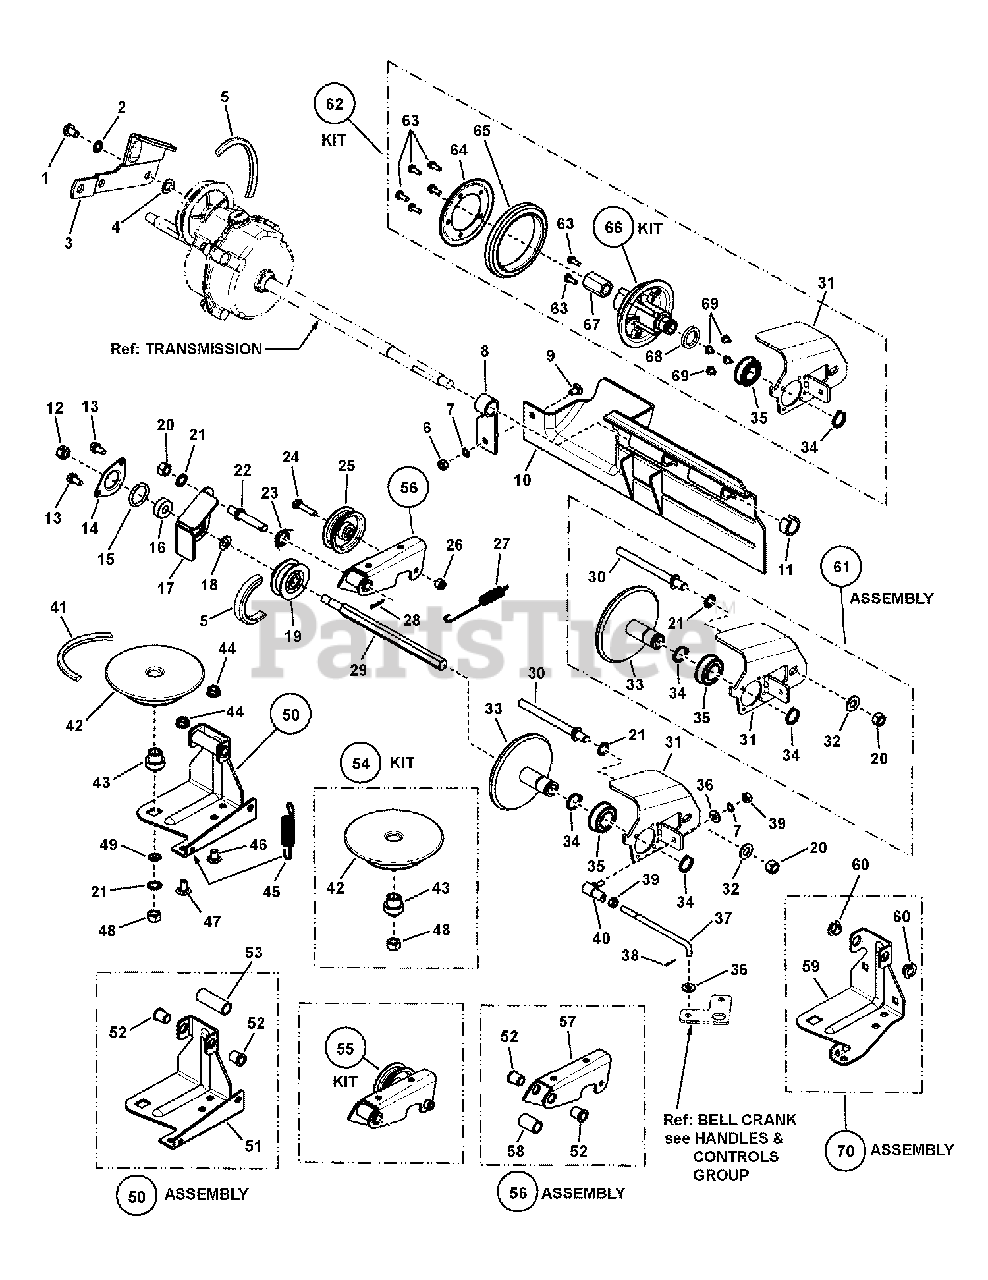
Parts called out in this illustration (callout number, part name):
1	SCREW, 5/16-18 x 1/2" Pan Head Self-Tap (Torx)
2	WASHER, 5/16" Internal Tooth Lock
3	LINK, Differential (Comm.)
4	WASHER, 44 x .78 x .025 Curved
5	BELT, Poly-V
6	NUT, 1/4-20 Hex, GR 5
7	WASHER, 1/4" Internal Tooth Lock
8	SUPPORT, Foot Guard
9	BOLT, 1/4-20 x 1/2" Short Neck Carriage GR 5
10	FOOT GUARD, Rear
11	RING, Split (Black)
12	NUT, 3/8-24 Hex Center Lock, GR 5
13	SCREW, 1/4-20 x 1/2" Hex Flange Self-Tap
14	HOLDER, Bearing (Outer Half)
15	O-RING, V21
16	BALL BEARING, Spherical O.D., .38 I.D.
17	HOLDER, Bearing (Inner Half)
18	WASHER, .390 I.D. Flat
19	PULLEY, Poly-V (2" O.D.)
20	NUT, 3/8-24 Hex
21	WASHER, 3/8" Internal Tooth Lock
22	STUD, Idler (3/8-24 thread)
23	SPRING, Idler- Torsion
24	SCREW, 1/4-28 x 1-3/8" Hex Head Cap, GR 5
25	PULLEY, Idler, V21
26	NUT, 1/4-28 Hex Top Lock
27	SPRING, Clutch - 21S
28	COTTER PIN, 3/32 x 1/2"
29	SHAFT, Hex Drive
30	GUIDE, Thrust Plate (3/8-24 thread)
31	THRUST PLATE, Short
32	WASHER, 3/8" Flat
33	DISC, Driven (Cantilever)
34	RETAINING RING, .625 External
35	BALL BEARING, 3/4" Bore
36	WASHER, .28 x .63 x .06 Flat
37	LINK, Transfer (1/4-28 thread)
38	COTTER PIN, .06 x .50 YZ
39	NUT, 1/4-28 Hex
40	BALL JOINT, 1/4-28
41	BELT, Engine Drive (Stretch)
42	DRIVE DISC, Steel
43	BUSHING, Powdered Metal (used for 1992 and earlier models)
43	BUSHING, Powdered Metal (used for 1993 and later models)
44	NUT, 5/16-18 Hex Flange Lock, GR 5 ZP
45	SPRING, Wheel Drive
46	BOLT, 5/16-18 x 1/2", Short Neck Carriage, GR 5
47	BOLT, 5/16-18 x 5/8" Short Neck Carriage GR 5
48	NUT, 3/8-16 Hex
49	RETAINER, 3/8" Bolt
50	ASSEMBLY, Deck Bracket (Incl. items 51, 52 & 53)
51	BRACKET, Deck, P21S
52	BUSHING, Flange, .381 x .625 x .62
53	SPACER, .500 x .65 x 1.75
54	KIT, Drive Disc Assembly (Includes Items 42, 43 & 48)
55	ASSEMBLY, Clutch Idler (Includes Items 24, 25, 26 & 56)
56	ASSEMBLY, Idler Arm (Includes Items 52, 57 & 58)
57	ARM, Clutch Idler
58	SPACER, Idler Arm
59	BRACKET, Deck - NLA ALONE (use Item 70 (59 & 60) or Item 50 (51, 52 & 53))
60	BUSHING, 3/8" I.D. Nylon
61	ASSEMBLY, Driven Disc (includes items 20, 21, & 30 thru 35)
62	ASS'Y, Driven Disc, Short, Commercial (Incl. same items as Kit 7061276 plus items 63, 64, 65)
63	SCREW, #10-24 x 1/2" Hex Washer Self-Tap (Torx)
64	SIDE PLATE, Drive Tire
65	DRIVEN RING (was 7010927)
66	KIT, Hub & Bushing (Incl. Items 20, 21, 30, 31, 32, 34, 35, 67, 68 & 69)
67	BUSHING, Drive, Hex
68	WASHER, Shim, .75 x 1.0 x .021
69	SCREW, #10-32 x 1/4" Hex Washer Self-Tap
70	ASSEMBLY, Deck Bracket (Incl. items 59 & 60)
71	ASSEMBLY, Thrust Plate & Bearing (includes items 31 & 35)
72	ASSEMBLY, Clutch Idler (Includes Items 24, 25, 26, 52 & 57)
